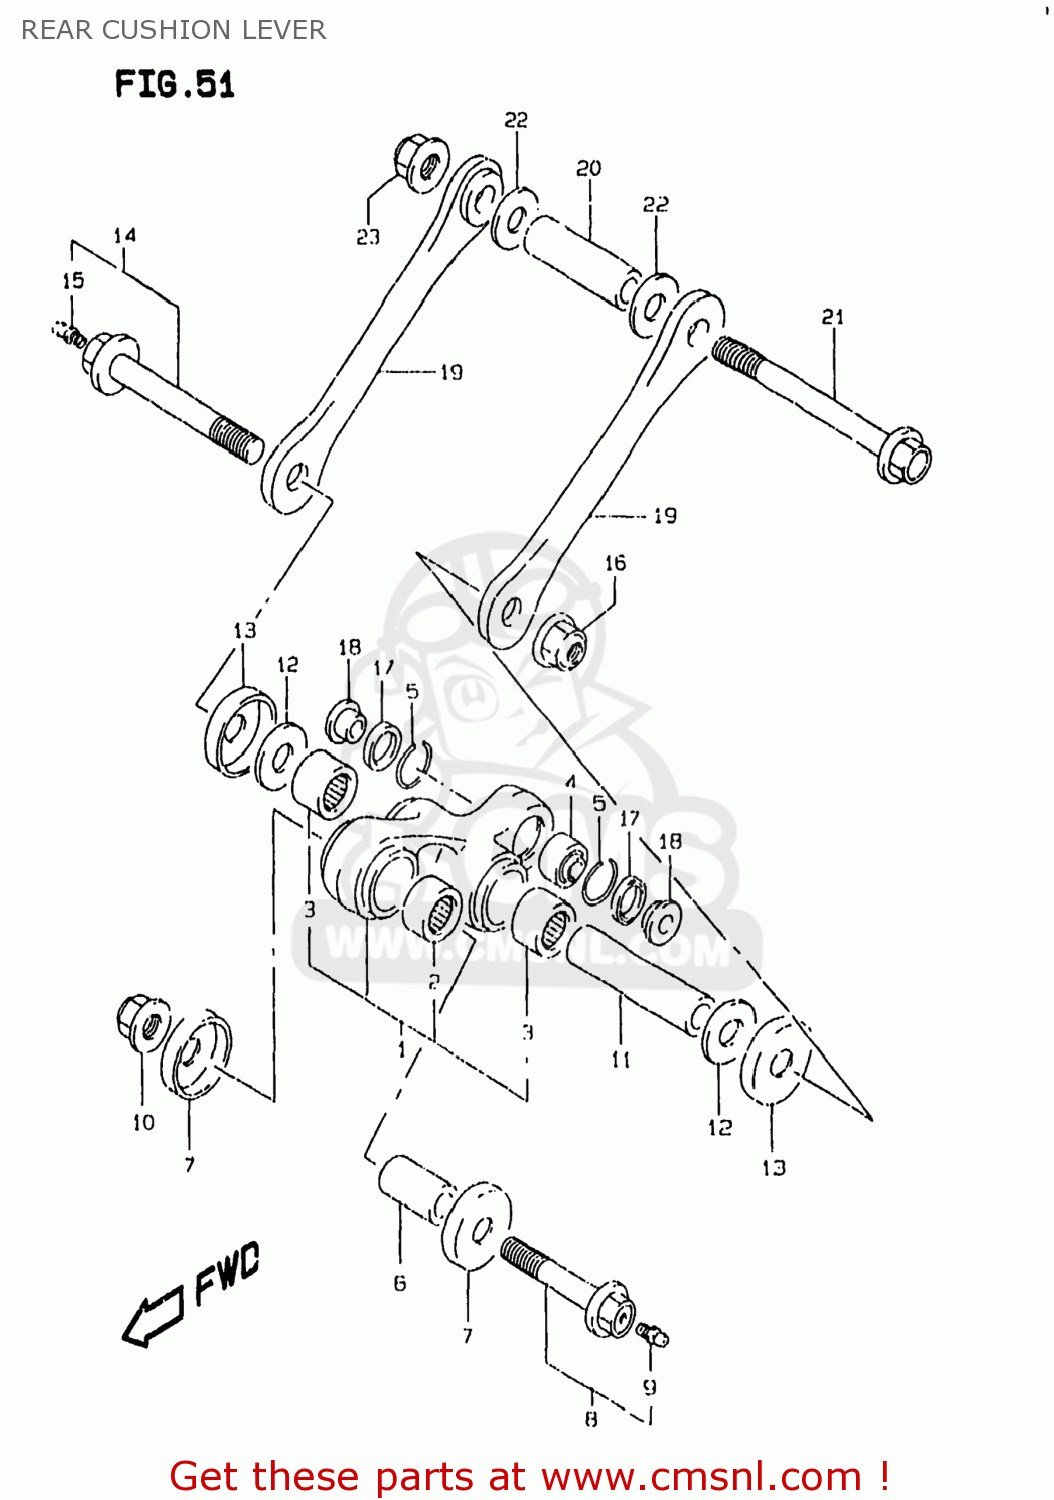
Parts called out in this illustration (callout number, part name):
1	LEVER SET,RR CUSHION
2	BEARING(20X27X32)
3	BEARING(20X27X23.5)
4	BEARING,RR CUSHION LEVER
5	RING,STOPPER
6	SPACER,RR CUSHION LEVER FR
7	SEAL,RR CUSHION LEVER FR DUST
8	BOLT,RR CUSHION LEVER FR
9	GREASE NIPPLE
10	NUT 12MM
11	SPACER,RR CUSHION LEVER CTR
12	WASHER
13	SEAL,RR CUSHION LEVER
14	BOLT,RR CUSHION LEVER CTR
15	GREASE NIPPLE
16	NUT
17	SEAL,OIL(17X24X3)
18	COLLAR
19	ROD,RR CUSHION
20	SPACER,RR CUSHION ROD
21	BOLT,RR CUSHION ROD
22	WASHER
23	NUT
